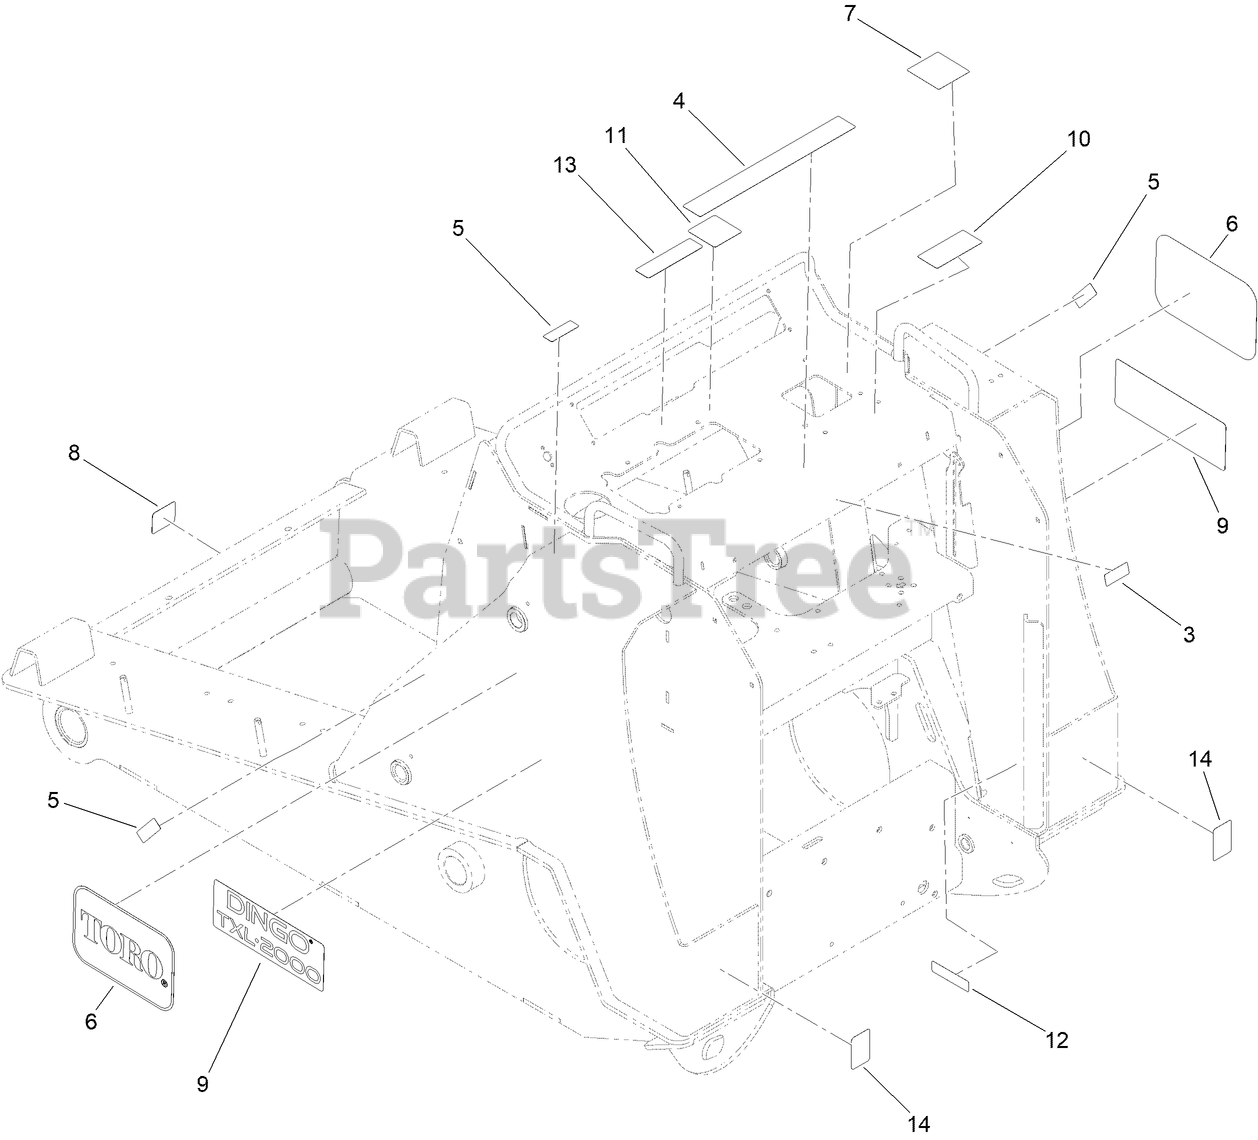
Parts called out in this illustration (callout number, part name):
3	DECAL-SURFACE, HOT
4	DECAL-SAFETY
5	DECAL-WARNING, PINCH POINT
6	DECAL
7	DECAL-CONTROL, LOADER
8	DECAL-TIE DOWN
10	DECAL-EXTENDED ARM SAFETY
11	DECAL-CONTROLS, LOADER
12	DECAL-ARRESTOR, SPARK
13	DECAL-ARM,RAISED
14	REFLECTOR
